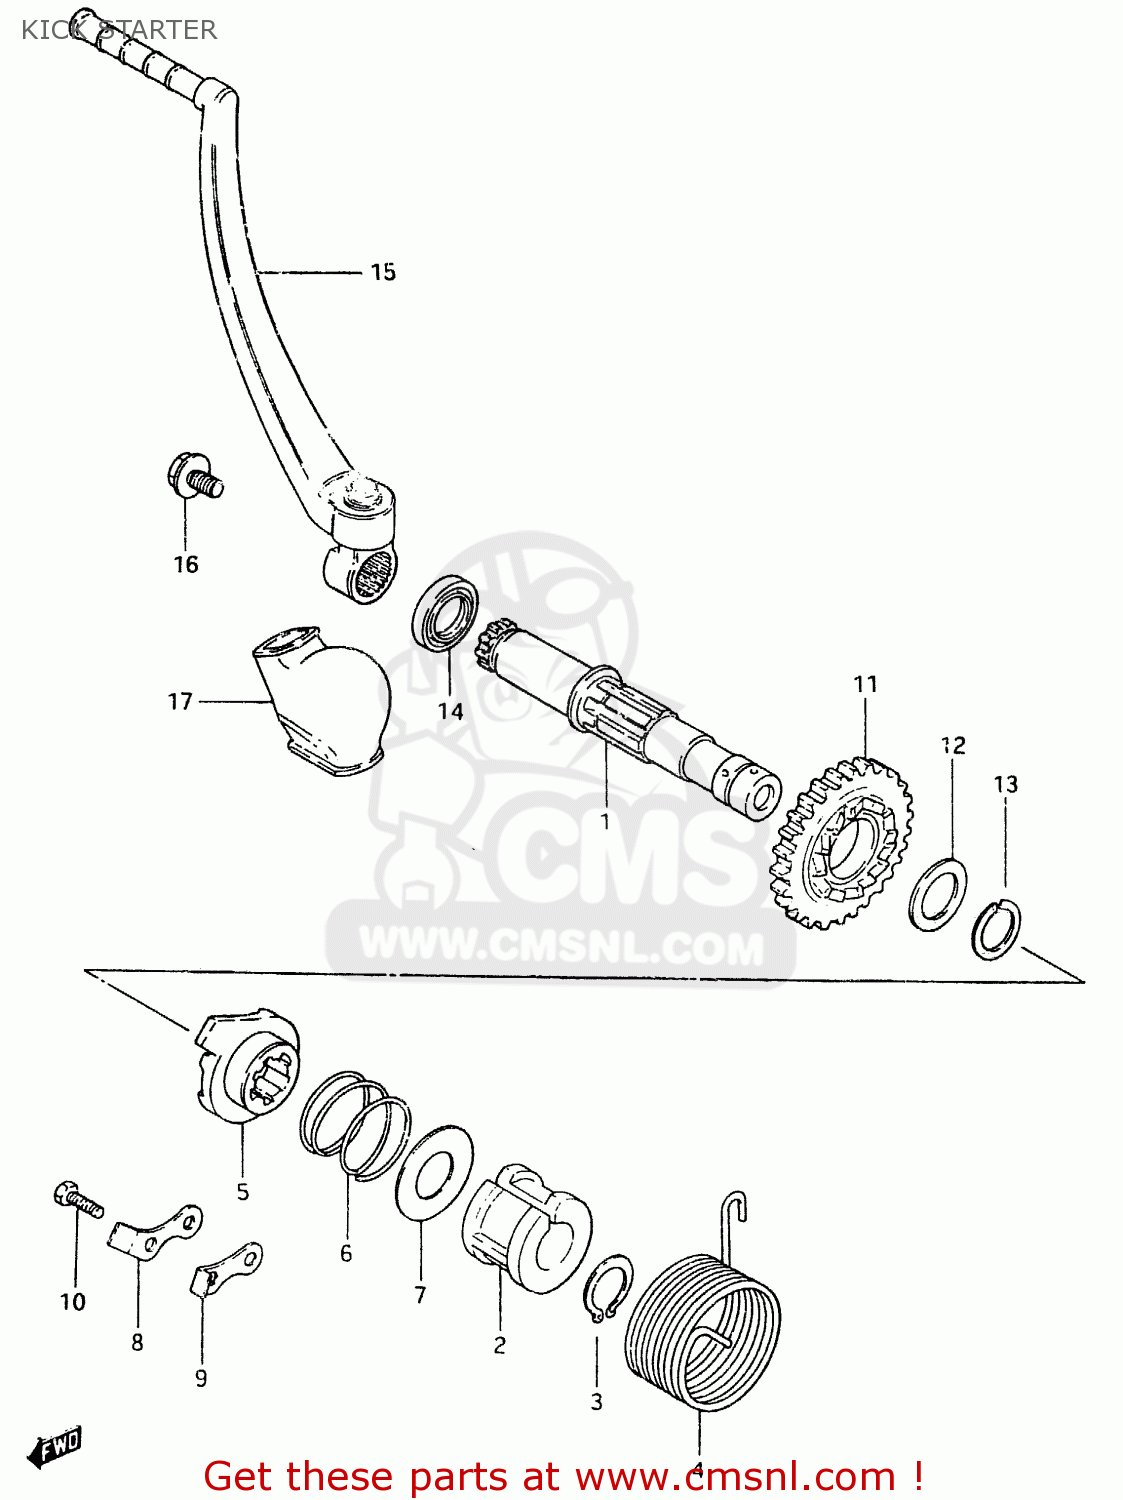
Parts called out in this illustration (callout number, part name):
1	SHAFT,KICK STARTER
2	GUIDE,KICK STARTER SFT SPRING
3	CIRCLIP
4	SPRING
5	STARTER,KICK
6	SPRING
7	WASHER
8	GUIDE,KICK STARTER
9	STOPPER,KICK STARTER
10	BOLT(8X20)
11	GEAR,KICK STARTER DRIVE
12	SHIM
13	CIRCLIP
14	SEAL,OIL(20X27X5)
15	LEVER ASSEMBLY,KICK STARTER
16	BOLT(8X14)
17	COVER,KICK STARTER LEVER JOINT
